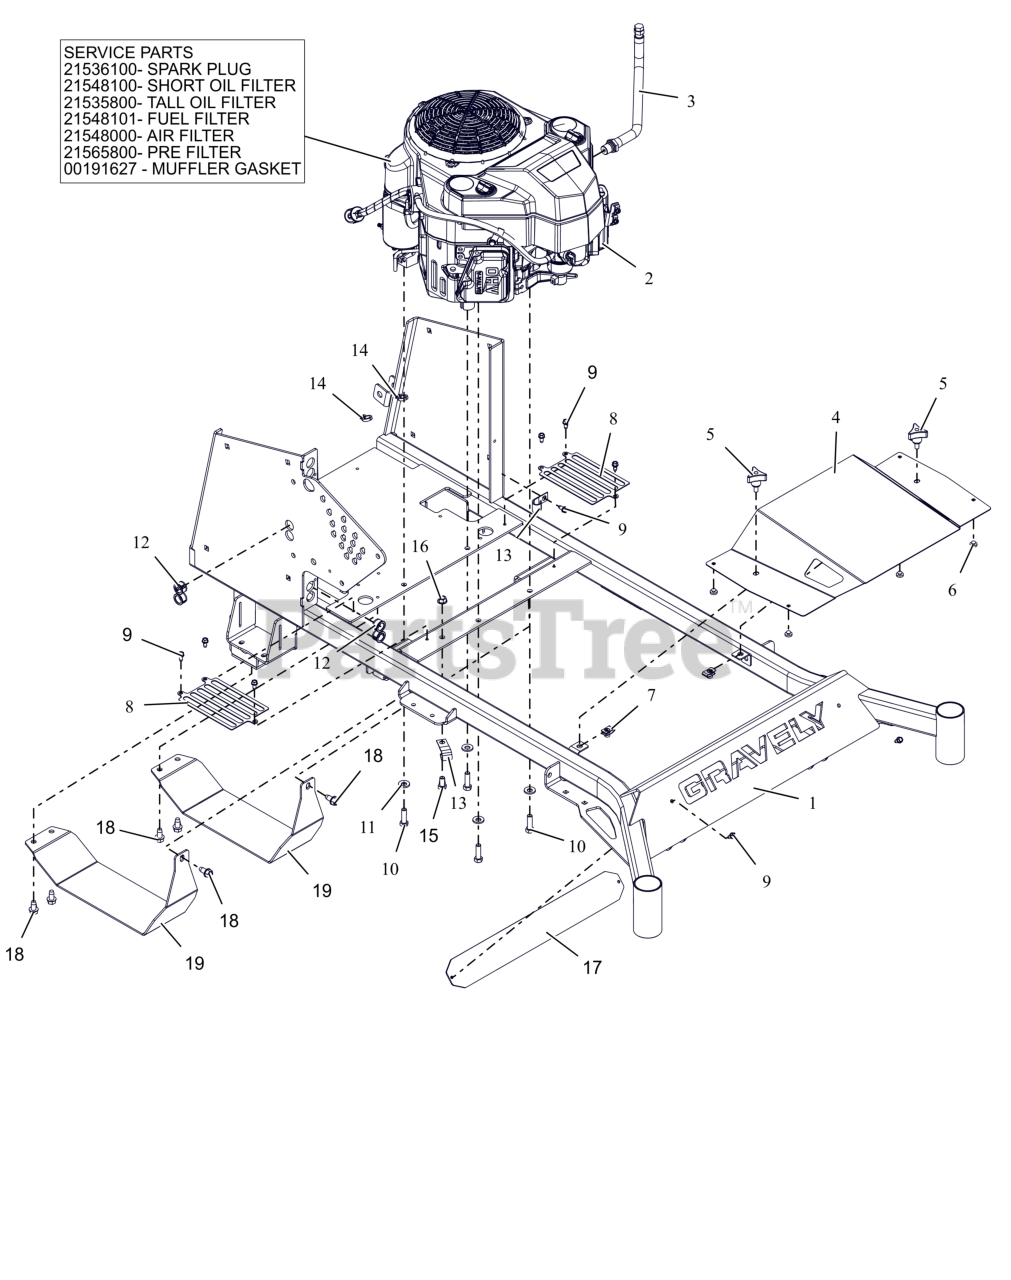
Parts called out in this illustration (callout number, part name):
1	48-52" MAIN FRM WLDMT W/SAFRTY
2	ENGINE- KAW FS651V
2	PLUG, SPARK
2	OIL FILTER, KAWASAKI FR
2	FILTER,OIL - KAW
2	FUEL FILTER-KAWASAKI FR
2	AIR FILTER, KAWASAKI FR
2	PRE FILTER, KAWASAKI FS
2	GASKET, MUFFLER S/O
3	HOSE, OIL DRAIN
4	48-52" BELT CVR W/SAFETY DCLS
5	KNOB,WING STUD 5/16-18 X .75
6	BUMPER GROMMET
7	NUT-CLIP RETAINER 5/16-18X.56
8	GUARD- TRANSAXLE FAN (RED)
9	SCR-TAP .25-20X.50 HWH ZCC
10	BLT, HEX .38-16X1.25 G5 ZCC NT
11	WASHER, 3/8" SPRING DISC
12	BUSH, PANEL SNAP .687X.875X.56
14	CLIP- PUSH-IN X-MAS TREE CABLE
15	BLT,HEX .38-16X.75 G5 ZCC
16	NUT-LK-CTR-FLG .375-16 GF ZCC
17	BUMPER LOGO BACKING PLATE -BLK
18	SCR,TAP .375-16X.75 HWH TR ZCC
19	BRKT-48-52" SKID PLATE (BLACK)
